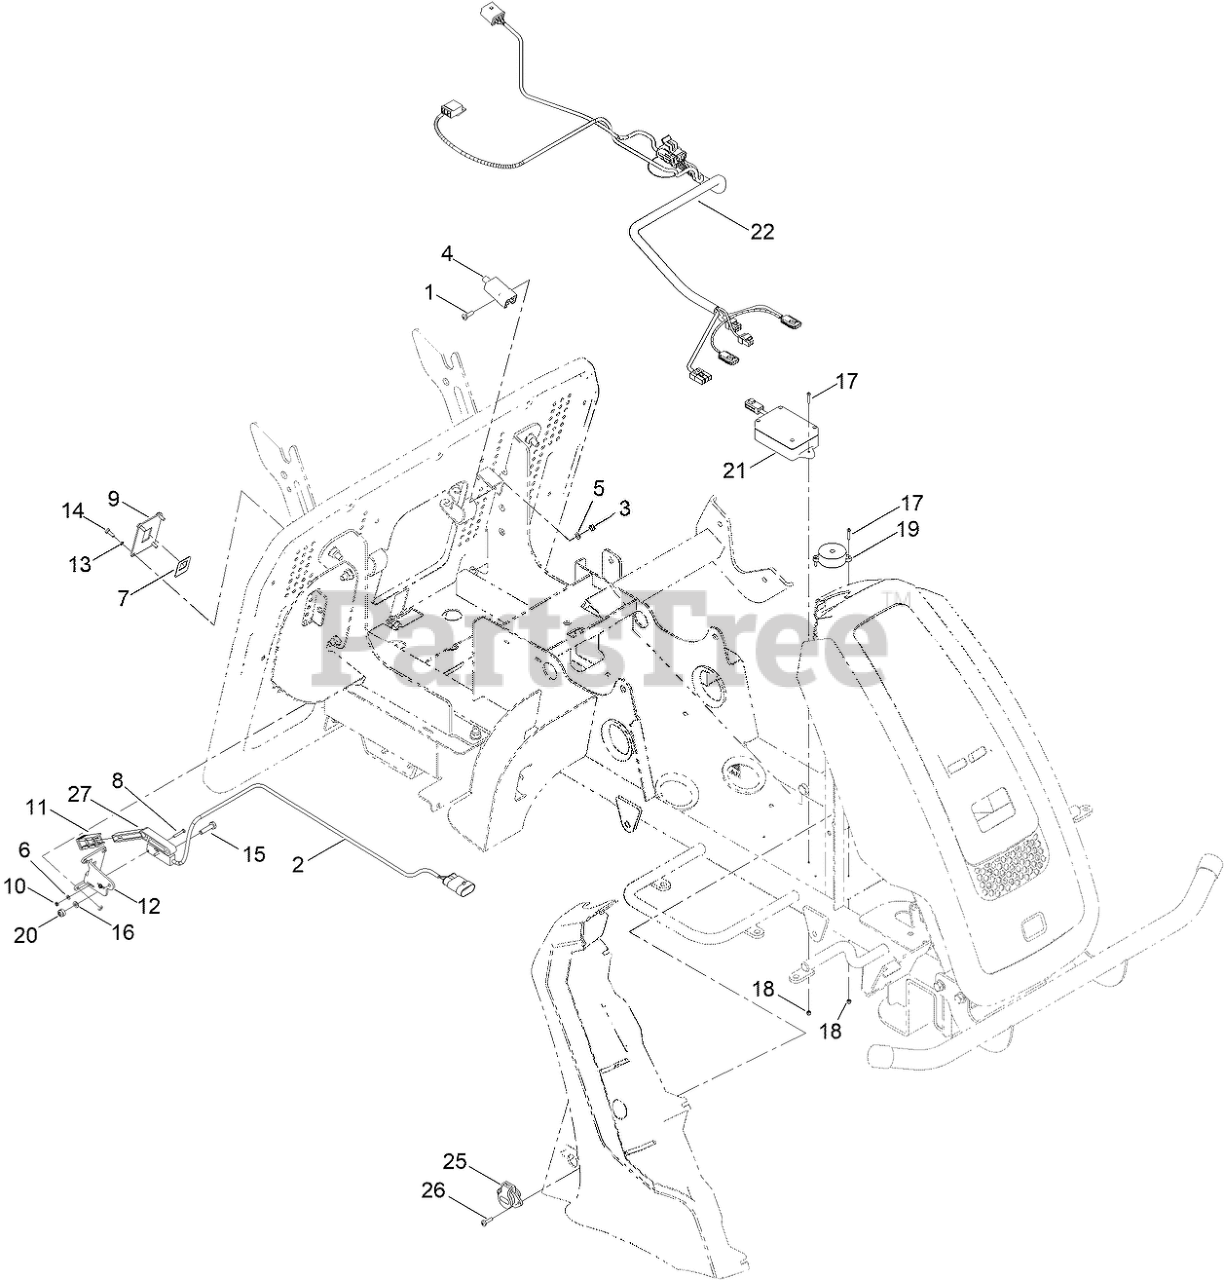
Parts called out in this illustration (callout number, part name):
2	SWITCH, GRASSBAG FULL
4	SENSOR, GRASSBAG INTERLOCK
5	WASHER
6	WASHER
7	PLATE, GRASSBAG FULL
9	PLATE, GRASSBAG FULL
11	EXTENDER, GRASSBAG FULL
12	BRACKET, GRASSBAG FULL
13	WASHER
15	SCREW-HH
16	WASHER
18	NUT-NYLOC
20	NUT-NYLOC
21	CONTROL BOX, DISPLAY
22	WIRING HARNESS (CONNECTION)
25	PORT, CHARGING
27	INDICATOR LEVER
